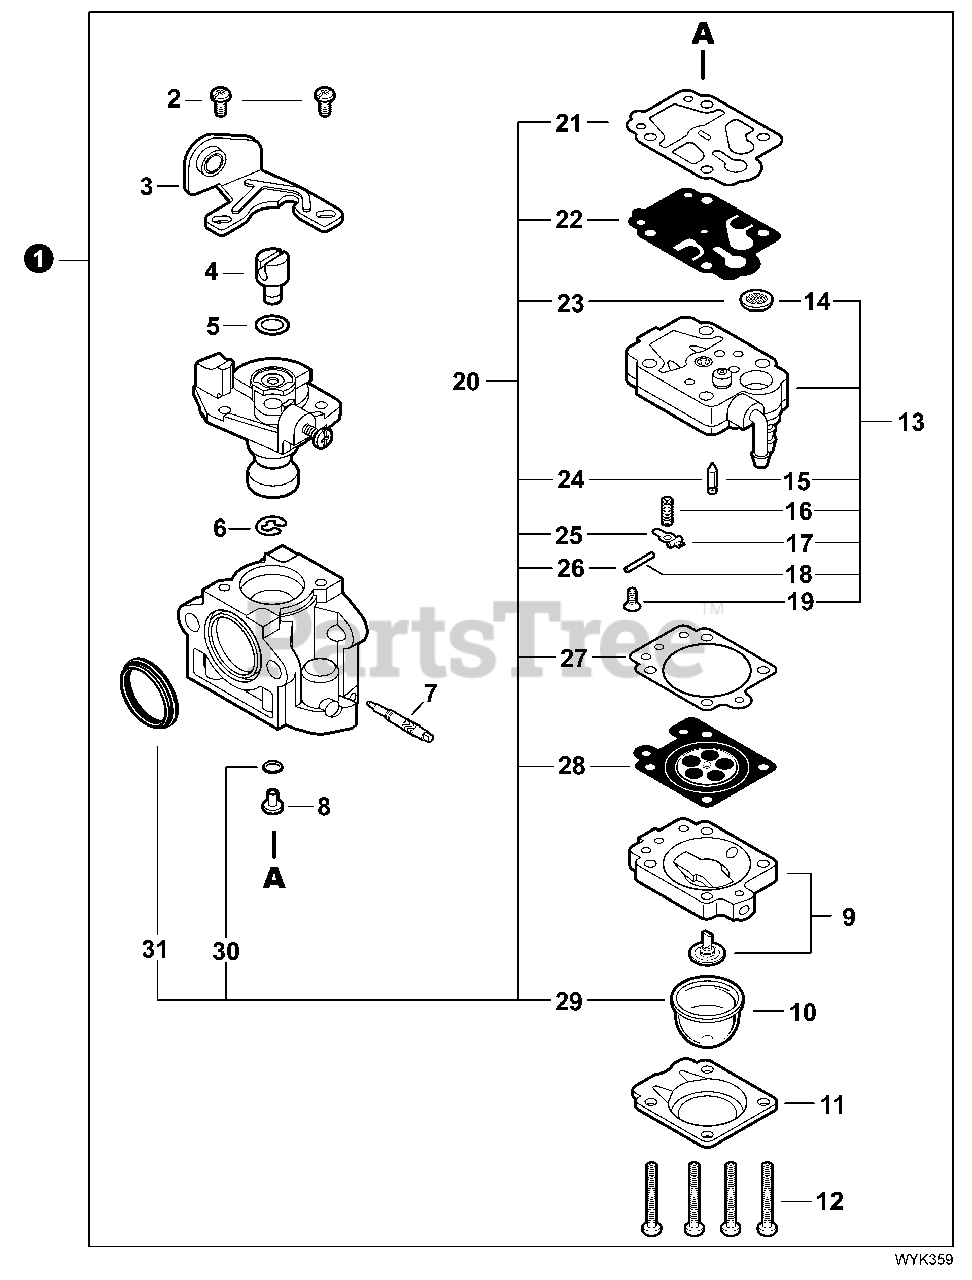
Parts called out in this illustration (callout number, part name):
1	CARBURETOR - WYK-359
3	BRACKET, THROTTLE CABLE
7	NEEDLE, HIGH SPEED
8	JET, MAIN #31
9	BODY ASSY, PURGE
10	BULB, PURGE
11	RETAINER, PURGE BULB
13	BODY ASSY, PUMP
14	SCREEN, INLET
15	VALVE, INLET NEEDLE
16	SPRING, METERING LEVER
17	LEVER, METERING
18	PIN, METERING LEVER
19	SCREW
20	REPAIR KIT, CARBURETOR
21	GASKET, PUMP
22	DIAPHRAGM, PUMP
23	SCREEN, INLET
24	VALVE, INLET NEEDLE
25	LEVER, METERING
26	PIN, METERING LEVER
27	GASKET, METERING DIAPHRAGM
28	DIAPHRAGM, METERING
29	BULB, PURGE
30	O-RING
31	RING, PACKING
